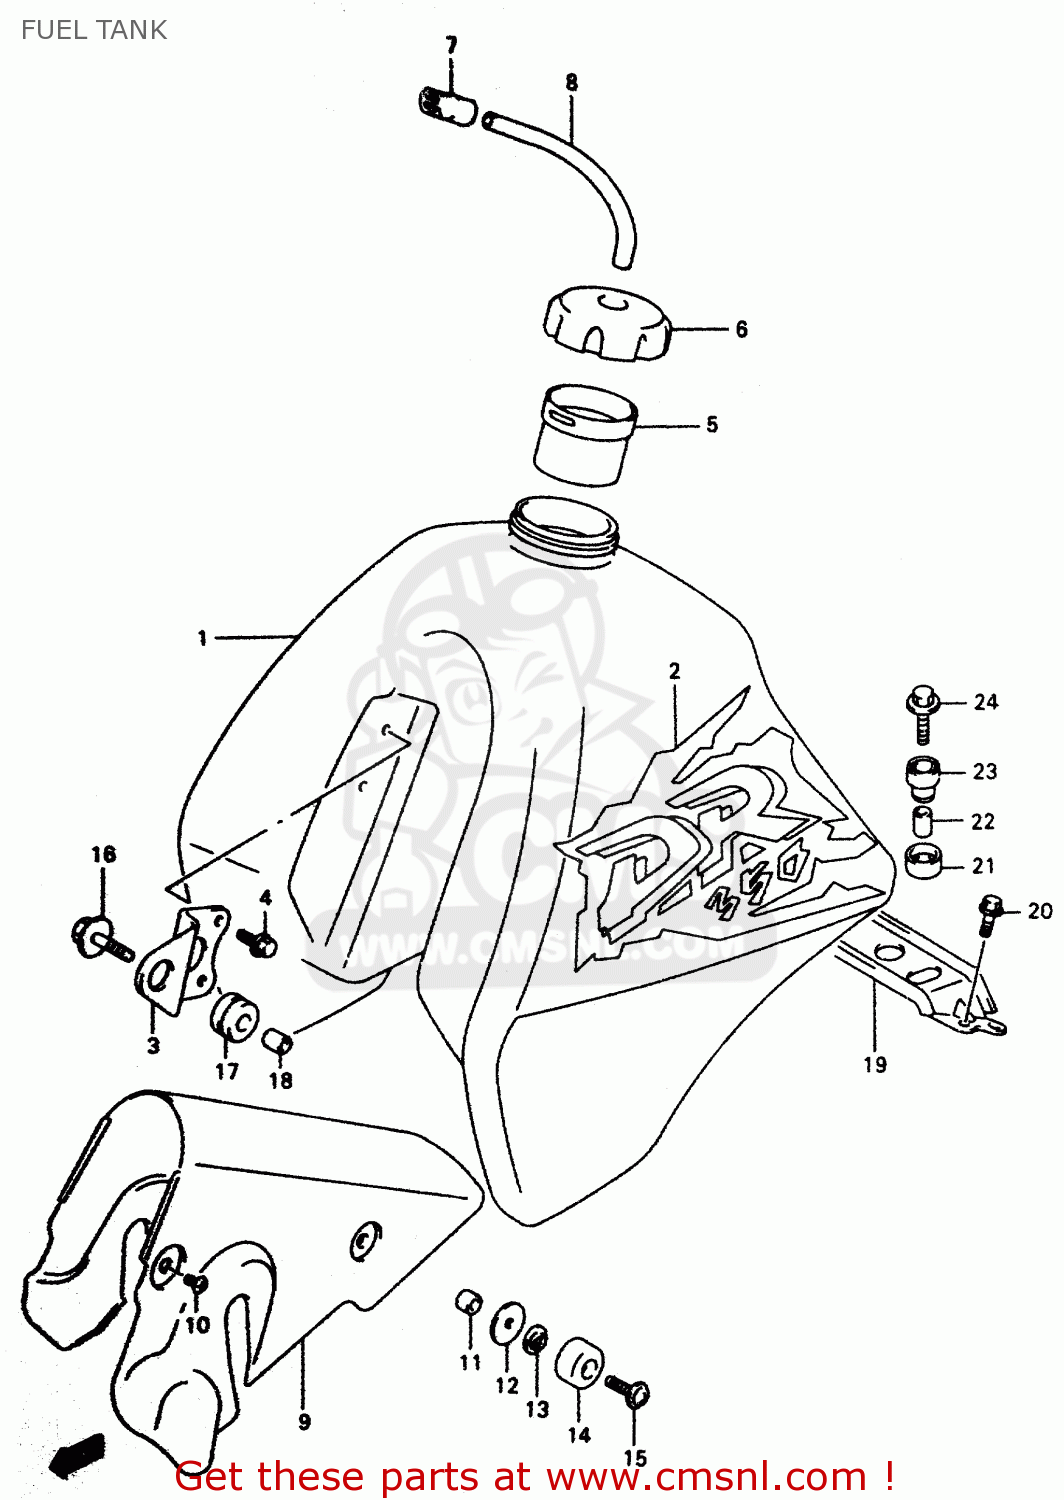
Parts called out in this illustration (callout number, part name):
1	TANK ASSEMBLY,FUEL
2	TAPE SET,FUEL TANK
3	BRACKET,FUEL TANK,FRONT
4	BOLT
5	TUBE,FILLER INLET
6	CAP ASSY,FUEL TANK
7	CLAMP,BREATHER HOSE
8	HOSE(5X8.2X600)
9	HEAT SHIELD,FUEL TANK
10	BOLT
11	SPACER(6.1X14X7.2)
12	WASHER (6.5X26X2.3)
13	WASHER
14	CUSHION
15	SCREW
16	BOLT(8X25)
17	CUSHION
18	SPACER(8.5X12X12.5)
19	BRACKET,FUEL TANK RR
20	BOLT
21	CUSHION
22	SPACER(6.5X9X18)
23	CUSHION
24	BOLT(6X30)
